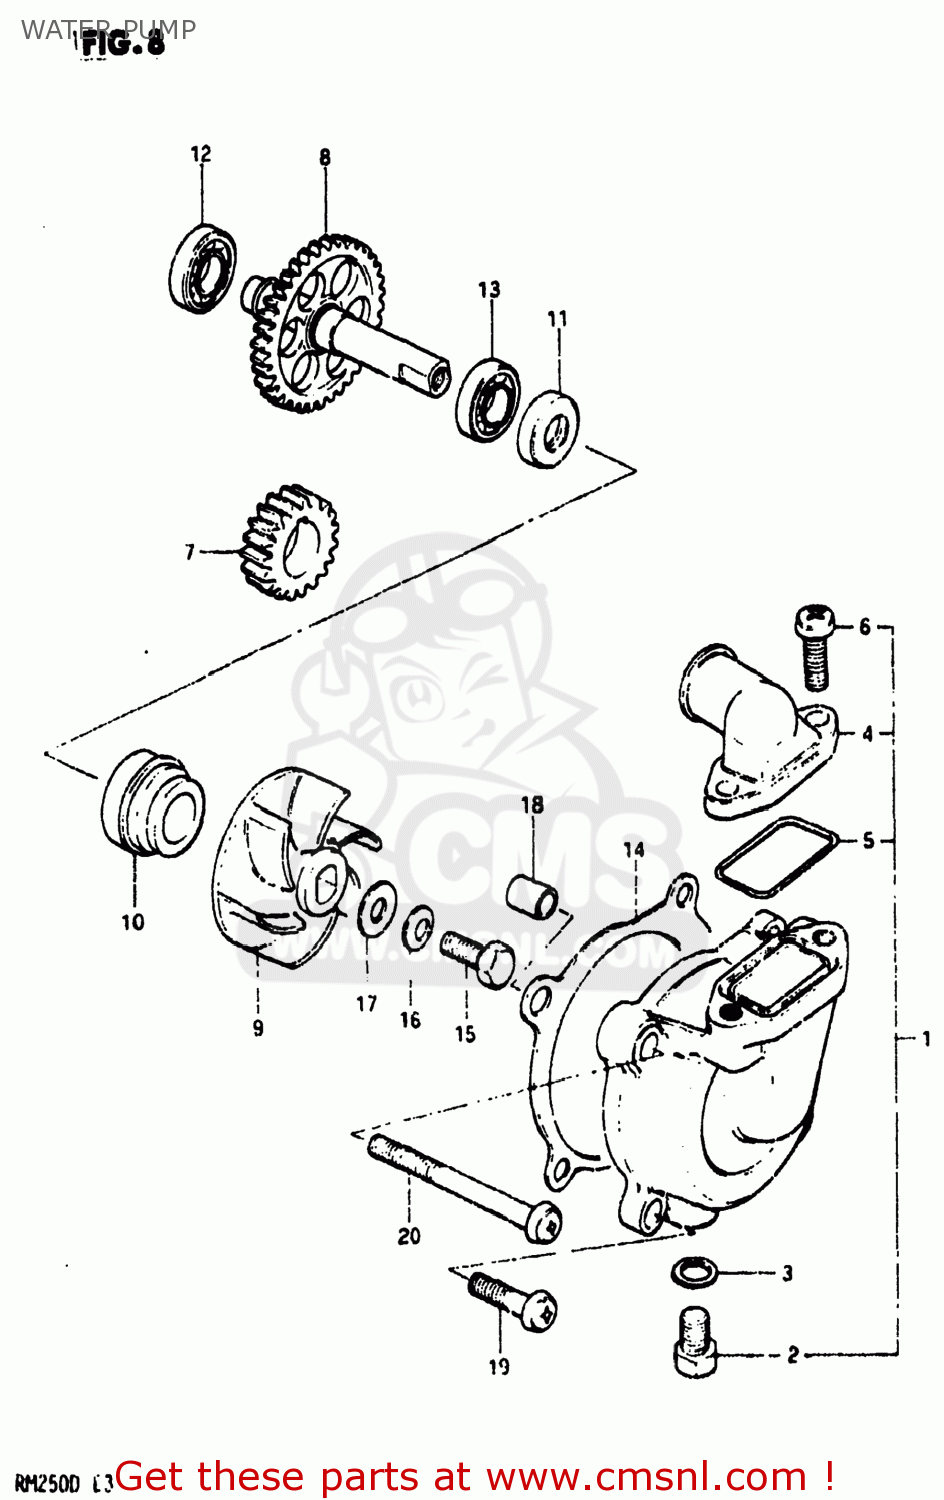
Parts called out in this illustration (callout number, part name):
1	CASE,WATER PUMP
2	BOLT,DRAIN
3	GASKET,DRAIN (NAS)
4	CONNECTOR
5	O RING,WATER PUMP CONNECTOR
6	SCREW
7	GEAR,WATER PUMP DRIVE
8	GEAR,WATER PUMP DRIVEN(NT:36)
9	IMPELLER,WATER PUMP
10	SEAL,WATER PUMP SHAFT
11	SEAL,OIL(10X21X5)
12	BEARING(10X22X6)
13	BEARING
14	GASKET,WATER PUMP CASE (MCA)
15	BOLT(6X13)
16	WASHER
17	GASKET (NAS)
18	PIN
19	SCREW
20	SCREW 6X60
